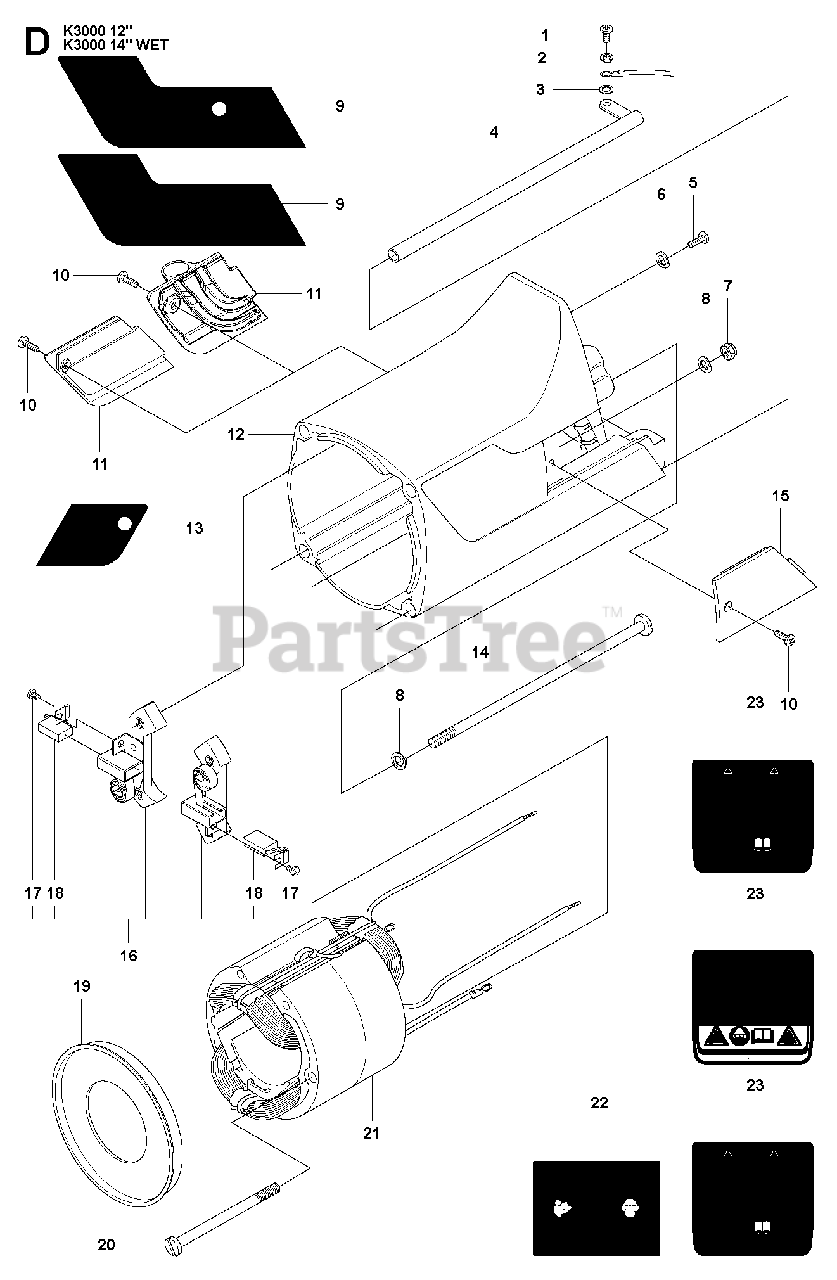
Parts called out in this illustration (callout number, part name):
1	SCREW CRPANM
6	SPRING WASHER
8	SPRING WASHER
9	LABELElectric
10	SCREW CCRPANT
12	MOTOR HOUSING
16	BRUSH HOLDERIncl. 17, 18
17	SCREW SLPANM
19	AIR STREAM DIRECTOR
21	STATOR ASSY100 - 120V
21	STATOR ASSY230V
23	LABELUSA, UK
23	LABELUSA, UK. Wet
